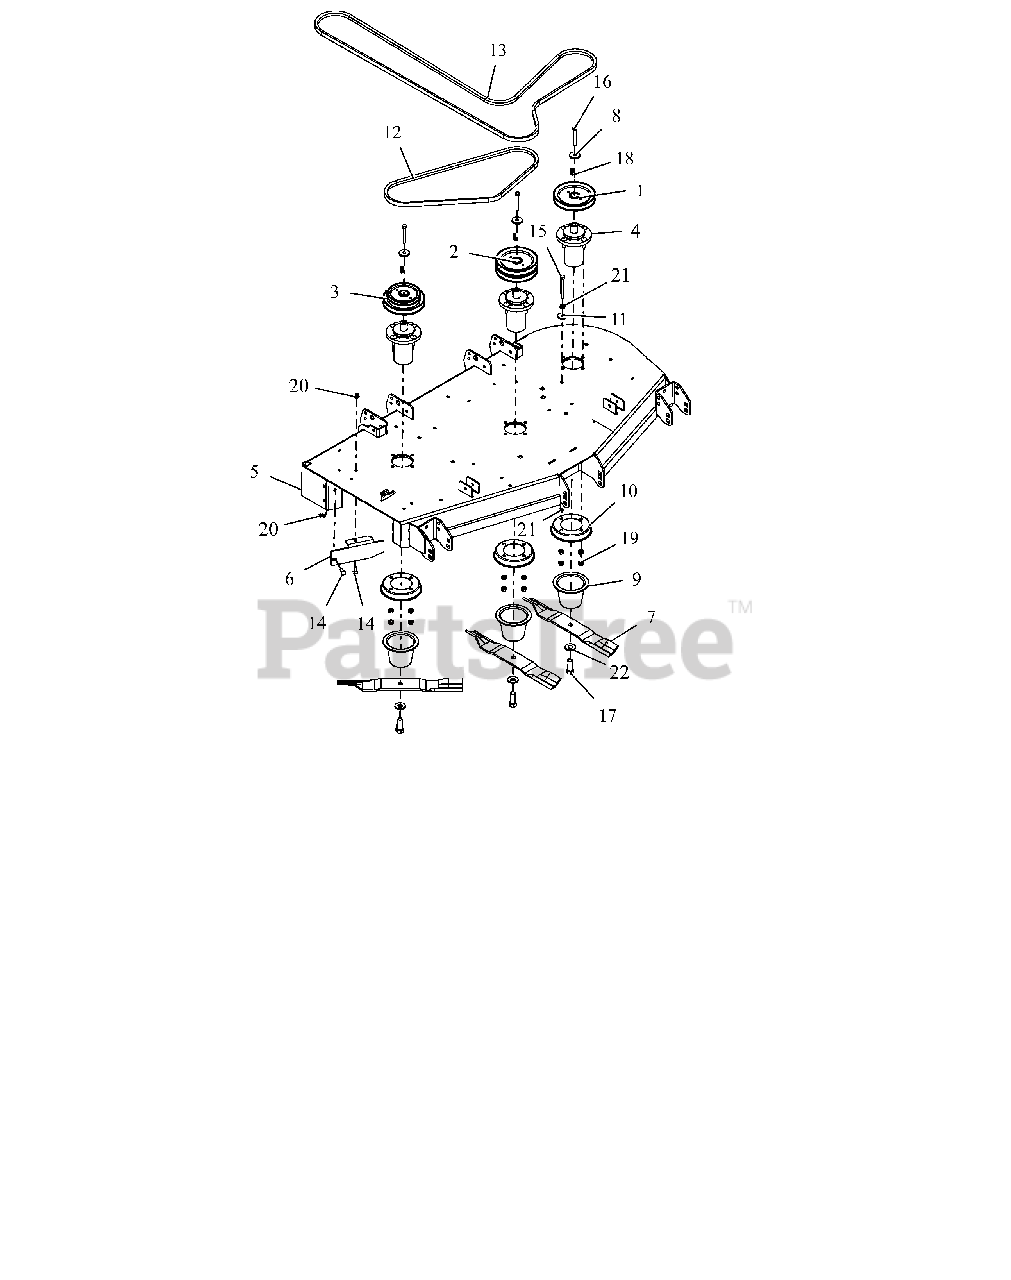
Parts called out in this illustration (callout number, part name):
1	PULLEY, SINGLE-1"ID X 6" OD
2	PULLEY, DOUBLE
3	PULLEY, DBL-1"IDX6.00"&4.75"OD
4	ASM, MAINT FREE ALUM SPINDLE
5	DECK, PT152 W/SAFETY DECALS
6	52" DISCHARGE BAFFLE - RED
7	BLADE, 18.00" MOWER (HI-LIFT)
8	RETAINER, SHEAVE
9	GUARD, SPINDLE LOWER
10	GUARD, SPINDLE TOP
11	WSHR-FL-STL .406X1.375X.135 YZ
12	V-BELT, B-COGGED
13	BELT, B-SECTI0N EPDM RAW EDGE
14	@BLT-RDHDSQNK .31-18X1.00 G5YZ
15	@BLT-HEX .38-16X3.50 GR5 YWZC
16	BLT-HEX .38-16X2.75 GR8 YWZC
17	BLT-HEX .62-18X1.75 GR8 YWZC
18	KEY, SQ .25X.25X1.00 RC 40-50
19	NUT-LK-CTR-FLG .38-16 YWZC
20	@NUT-LK-NYL-FLG .31-18 YWZC
21	@NUT-SPNLK-FLG .375-16 YWZC
22	WSHR-BLVL .669X1.535X.138
